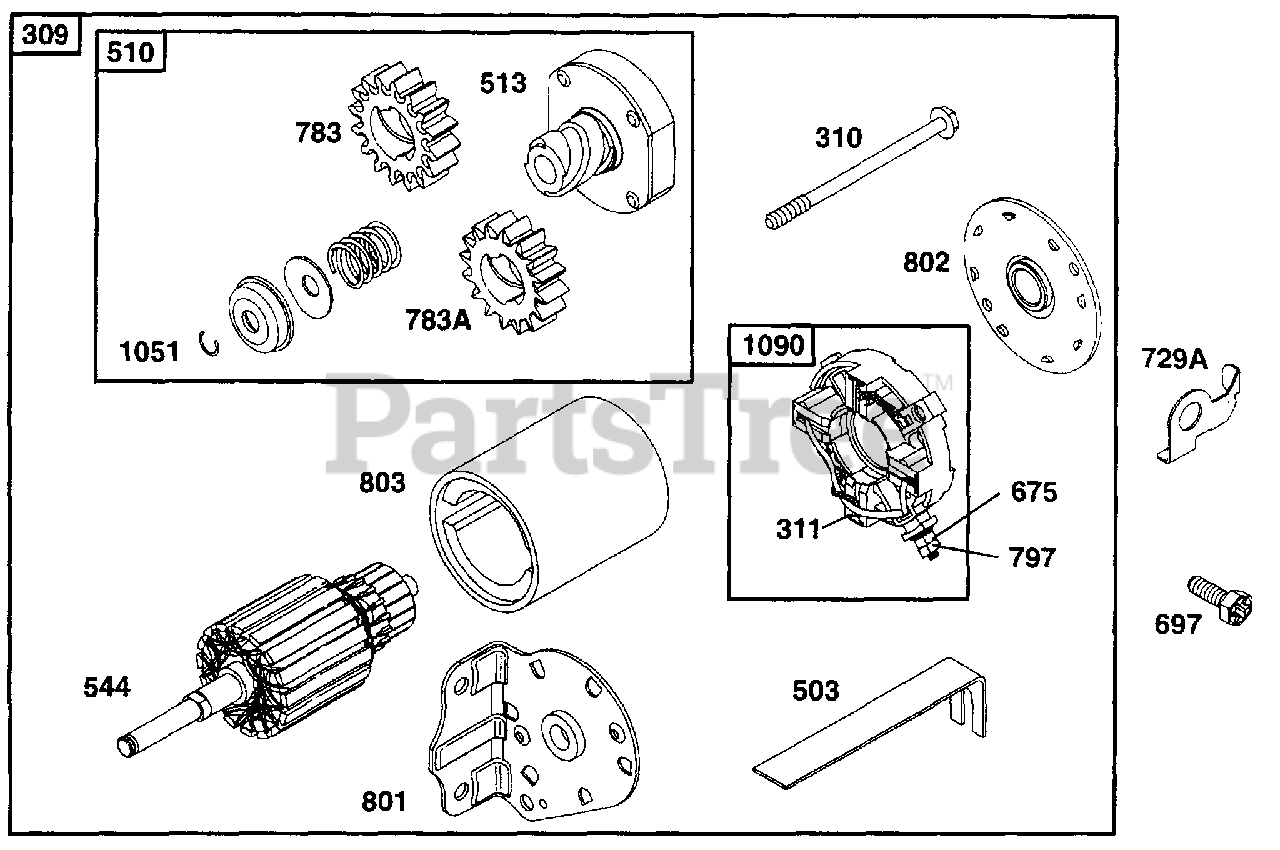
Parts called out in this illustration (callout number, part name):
309	Starter Motor
310	Hex Screw
503	Starter Strap
510	Starter Drive
513	Drive Clutch
544	Starter Armature
675	Flat Washer
697	Torx Screw
783	Starter Gear
783A	Starter Gear
797	Hex Nut
801	Drive Cap
803	Starter Housing
1051	Retaining Ring
1090	Brush Retainer
